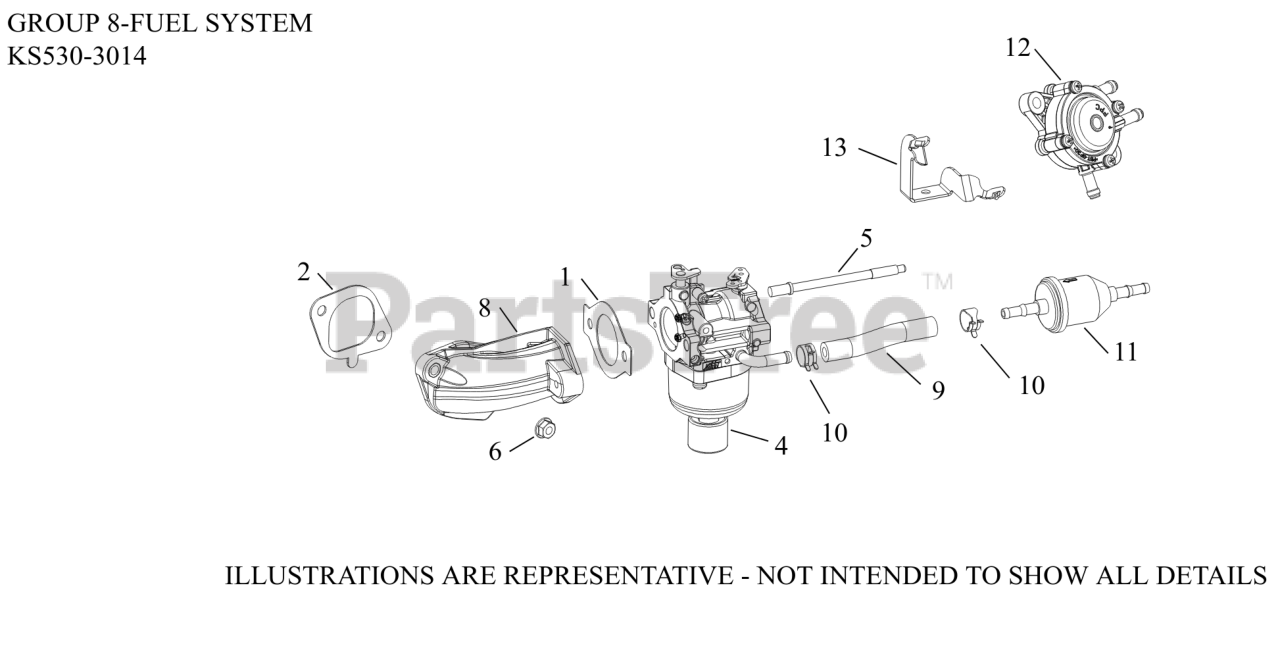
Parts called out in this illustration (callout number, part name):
1	GASKET, CARBURETOR (THROTTLE)
2	GASKET, INTAKE MANIFOLD
4	KIT,CARB(NIKKI)
5	STUD, CARBURETOR
6	NUT, FLG M6X1.0
8	MANIFOLD, INTAKE ASSEMBLY
9	HOSE,LW PERM.FUEL 24.00"-USE 25 111 81-S
10	SPRING CLAMP, HOSE
11	FILTER,FUEL 51 MICRON (FUEL PUMP)
12	PUMP, FUEL (PULSE)-(#2539326S)
13	BRACKET, FUEL PUMP
NI	HIGH ALTITUDE KIT (5000 FT)
NI	KIT, OVERHAUL
NI	KIT, CHOKE SHAFT
NI	KIT, O-RING
NI	KIT, SOLENOID (NIKKI)
NI	KIT, BOWL WITH O-RINGS
NI	KIT, FLOAT & INLET NEEDLE FOR FUEL PUMP
NI	KIT, THROTTLE SHAFT
